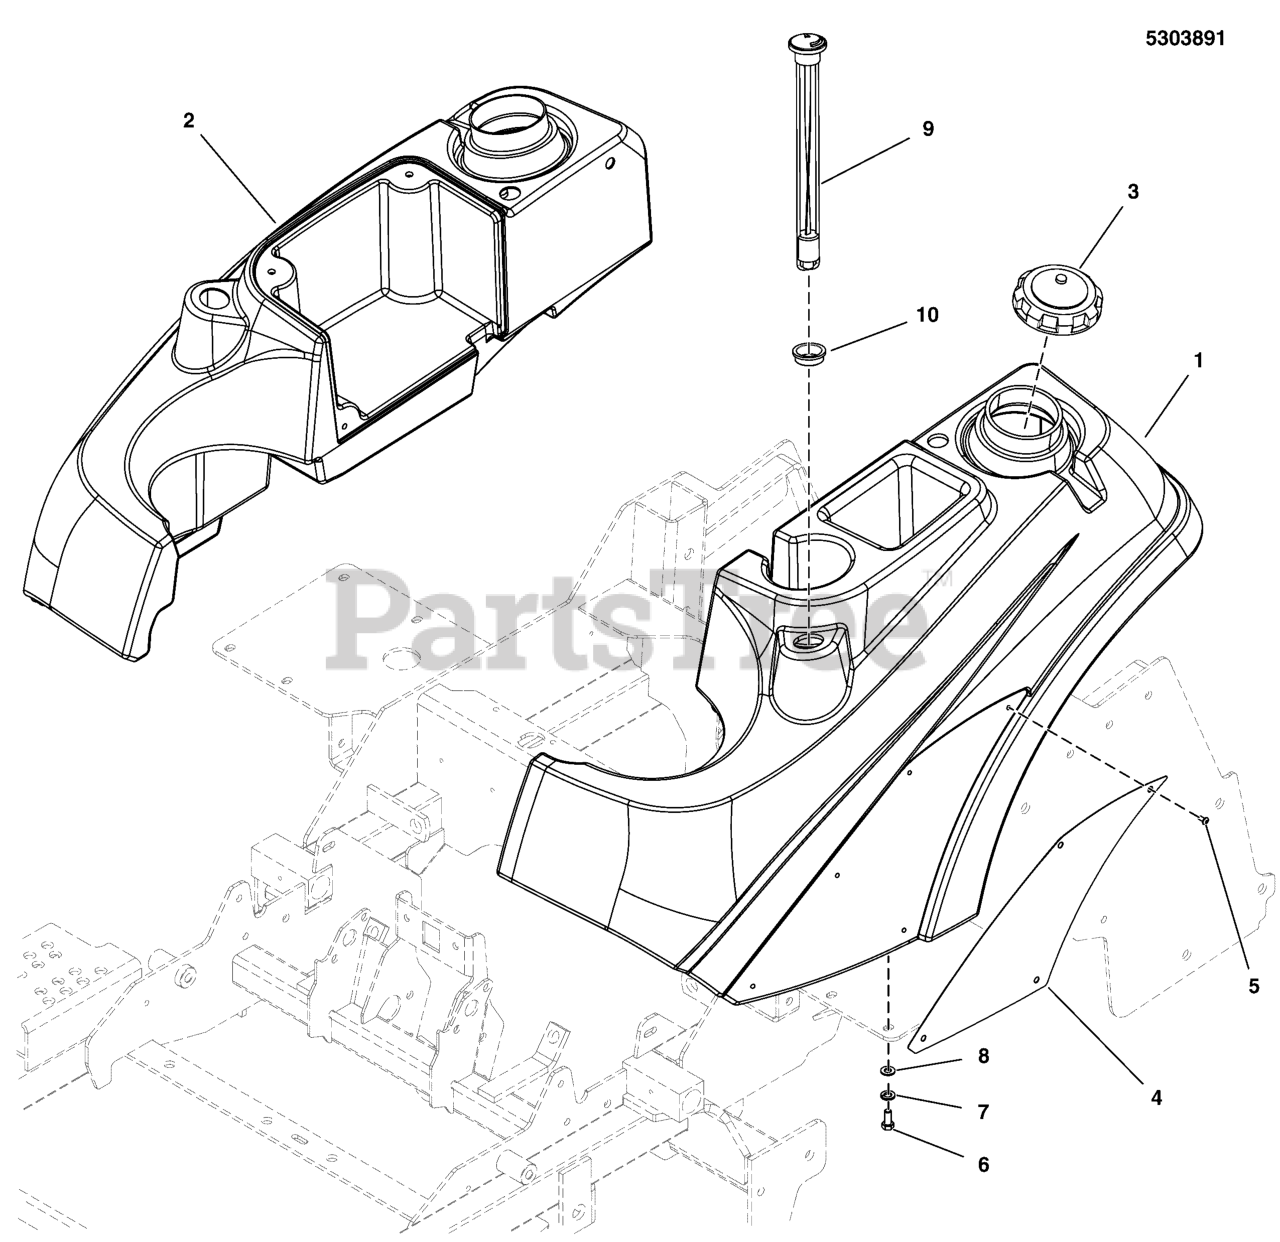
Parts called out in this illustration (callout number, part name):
1	TANK, FUEL, LH
2	TANK, FUEL, 5.25 GAL,MED, Z-RH, LOW PERM
3	FUEL CAP, 3-1/2", MANAGED VENT OUT, 12"
4	BADGE, IS2000 - IS3000 - RED
5	SCREW, #10-24 X 3/8 ALLEN BHBZ
6	BOLT, 5/16-18 X 3/4 GD5
7	WASHER, 5/16 LOCK CZ
8	WASHER, 5/16 F436 FLAT
9	GAUGE, FUEL, 12
10	GROMMET, FUEL GAUGE (SV)
